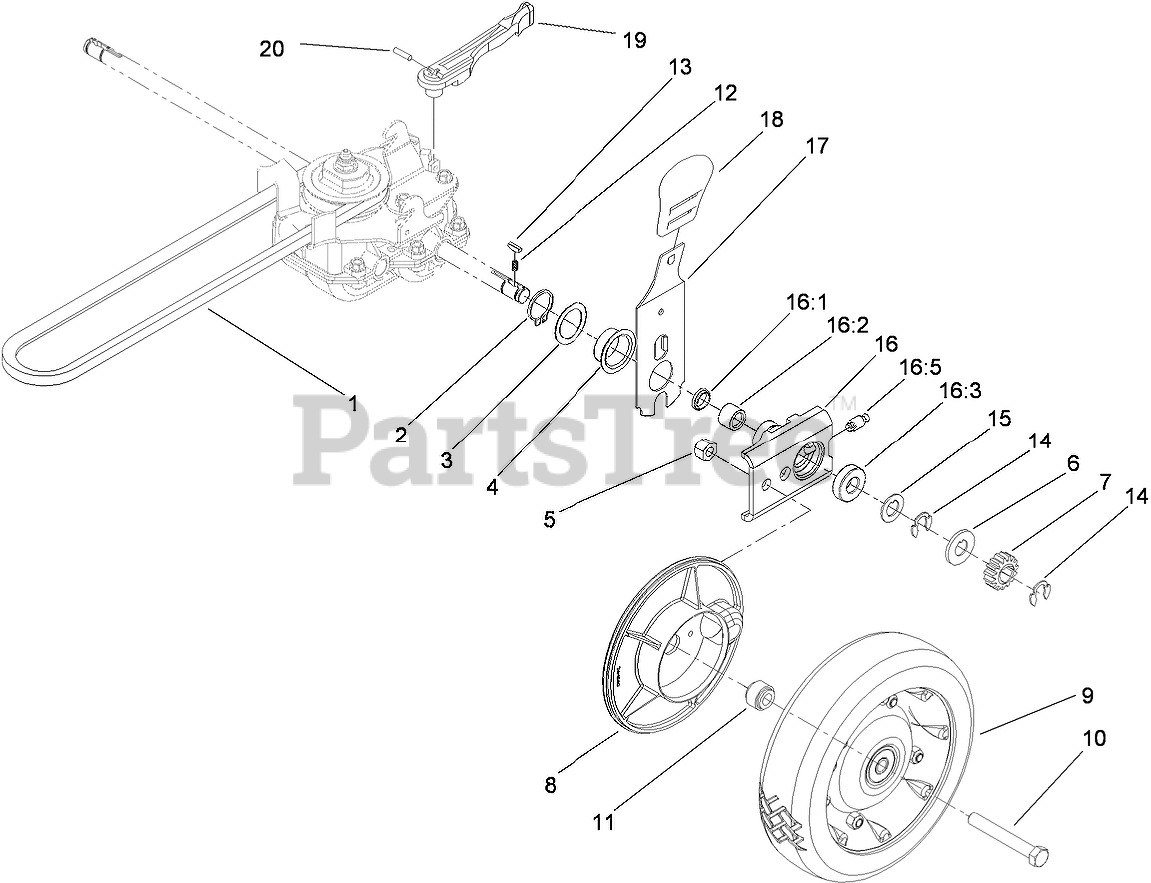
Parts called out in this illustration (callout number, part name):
1	V-BELT
2	RING-RETAINING
3	WASHER
4	CAP-END
5	NUT-LOCK, CONE
6	WASHER-THRUST, OUTER
7	GEAR-PINION
8	COVER-WHEEL
9	Wheel And Tire ASM
10	SCREW-HH
11	SPACER-COVER, WHEEL
12	SPRING-COMPRESSION
14	RING-RETAINING
15	WASHER-THRUST, OUTER
16	PIVOT ARM ASM
16:1	SEAL-OIL
16:2	BEARING-ROLLER
16:3	BEARING-WHEEL
17	REAR SPRING ARM ASM
18	KNOB-HOC
19	LEVER-SHIFT
20	PIN-COIL
